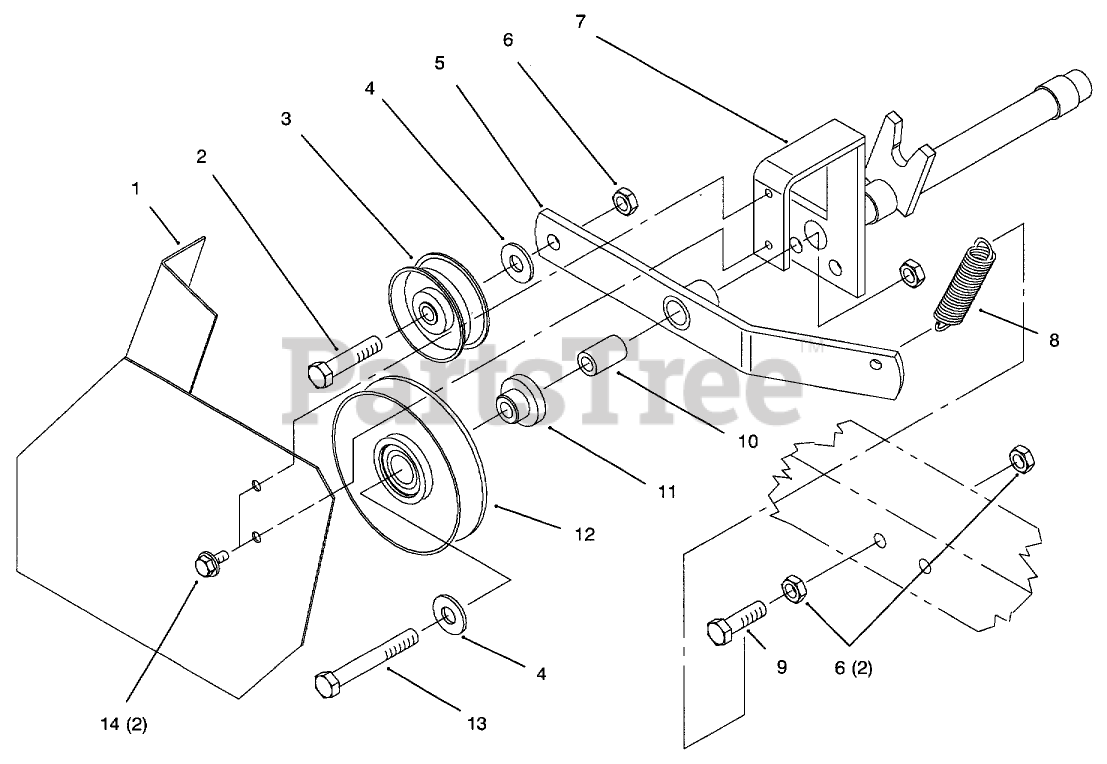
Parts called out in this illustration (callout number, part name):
1	ASM: FRONT IDLER R
2	SCREW-HH
3	IDLER PULLEY
4	WASHER-FLAT
5	ASSY IDLER ARM R
6	NUT-HEX
7	ASSY SUPPORT R
8	SPRING-BRAKE
9	SCREW-HH
10	SPACER
11	SPACER
12	PULLEY-IDLER
13	SCREW-HH
14	SCREW-HWH
